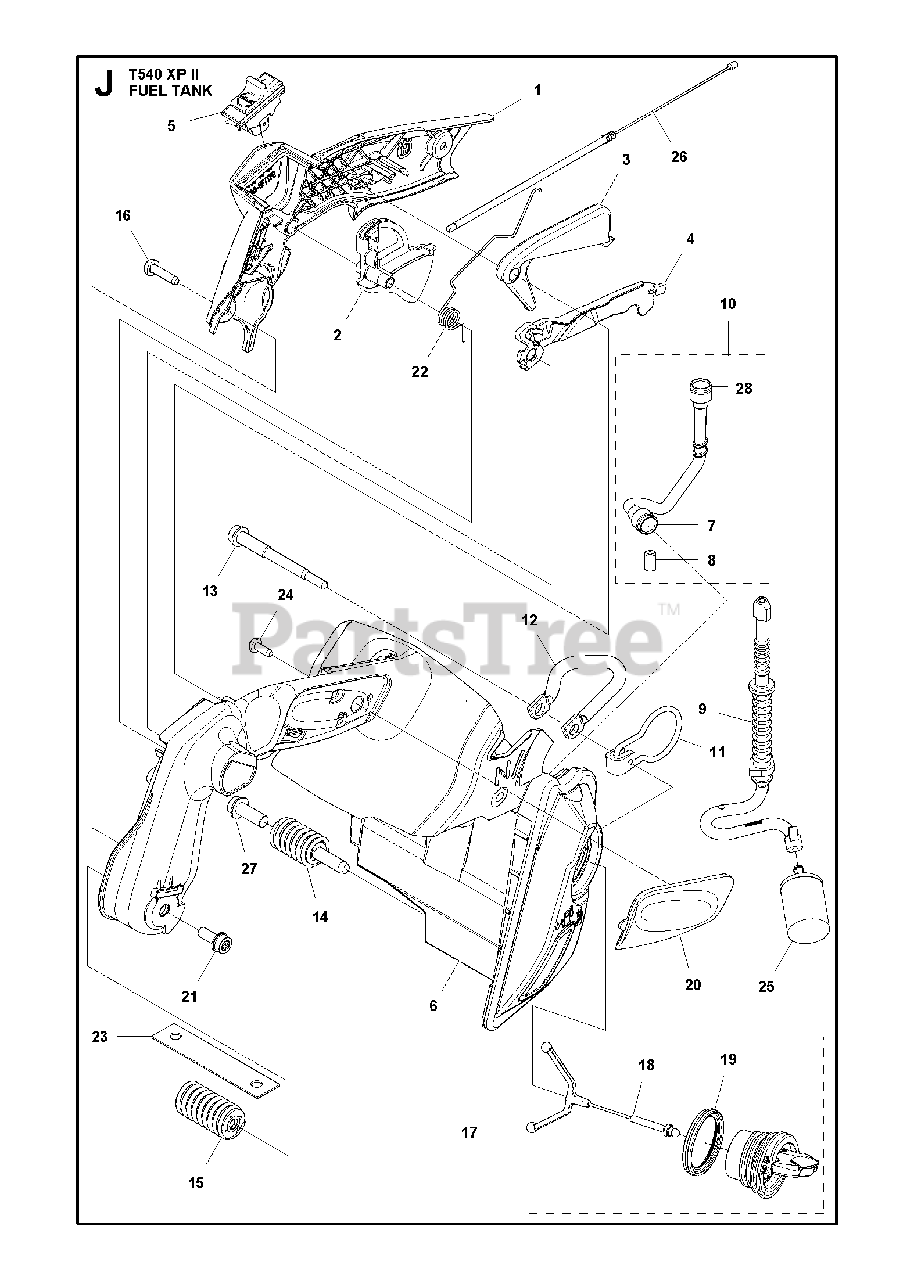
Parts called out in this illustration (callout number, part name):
1	LID
1	LID HANDLE XLARGE SIZE
2	THROTTLE CONTROL
3	THROTTLE LOCKOUT
4	CABLE COVER
5	STOP SWITCH
6	HANDLE HOUSING PART ASSY
7	TANK VENT ASSY 250 MBAR+
10	FUEL HOSE
13	SCREW ITXSCFM
14	ANTIVIBRATION ELEMENT
15	ANTIVIBRATION ELEMENT
16	SCREW CITXPANT
17	TANK CAP ASSY
18	TANK LOCK
19	SEALING
20	HANDLE INSERT
21	SCREW
24	SCREW CITXPANT
25	FUEL FILTER
26	THROTTLE CABLE ASSY
27	SCREW ITXSCFM
28	Fuel Filter Assembly
